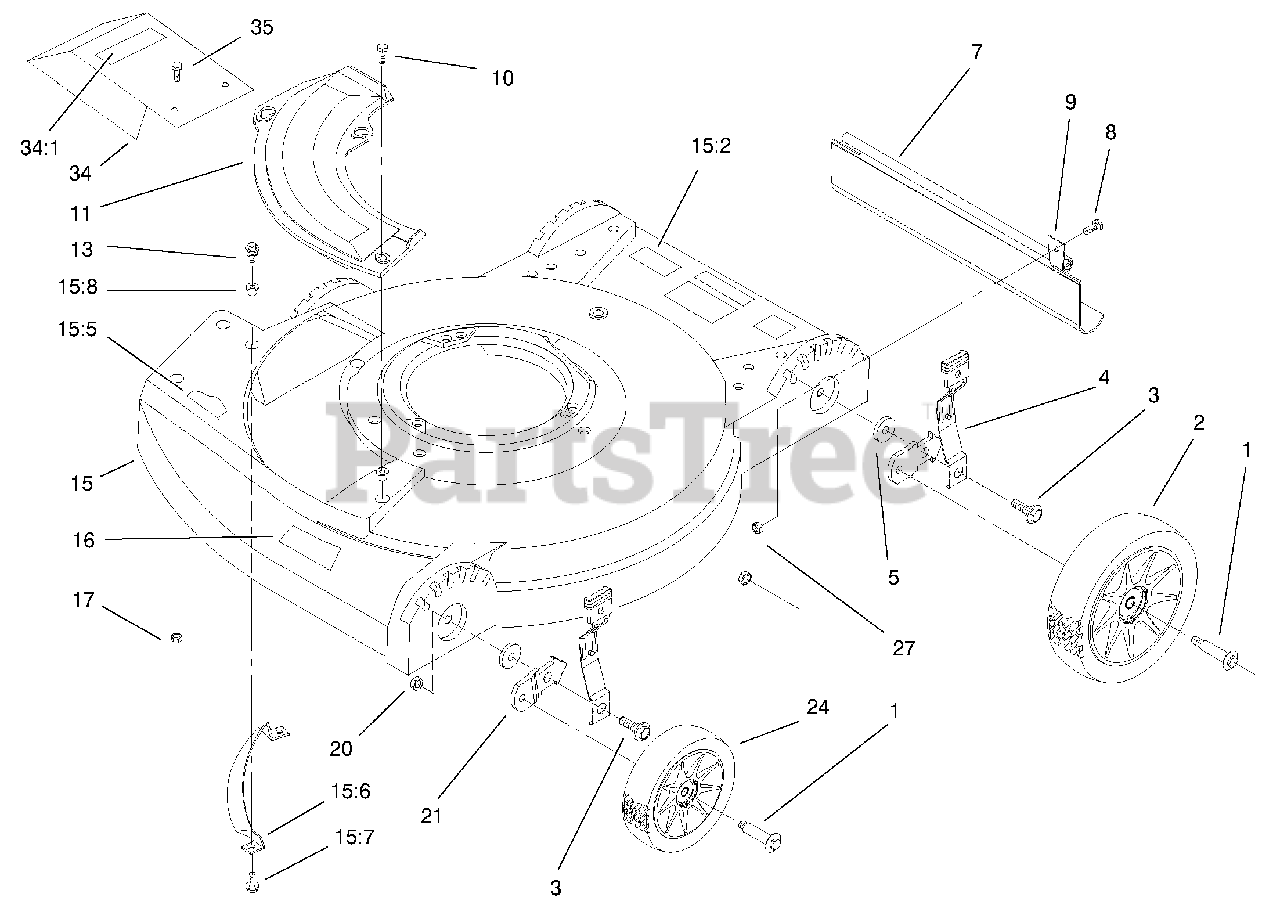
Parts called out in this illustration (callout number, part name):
2	Wheel/Tire ASM
4	Spring Arm ASM
7	Shield-Trailing
9	Clamp-Shield
10	Screw-Taptite
11	Plate-Chute Opening
13	Screw-Sems
15	Housing ASM
15:2	Decal-Danger
15:5	Decal-Danger
15:6	Toe Bar
15:7	Screw & Washer ASM
15:8	Grommet-Plastic
16	Decal-Deck, HP
17	Nut-Lock
20	Nut-Lock, NI
21	Bracket-Wheel Height
24	Wheel/Tire ASM
27	Nut-Lock, NI
34	Guard Plate
34:1	Decal-Deflector
35	Screw-Machine
